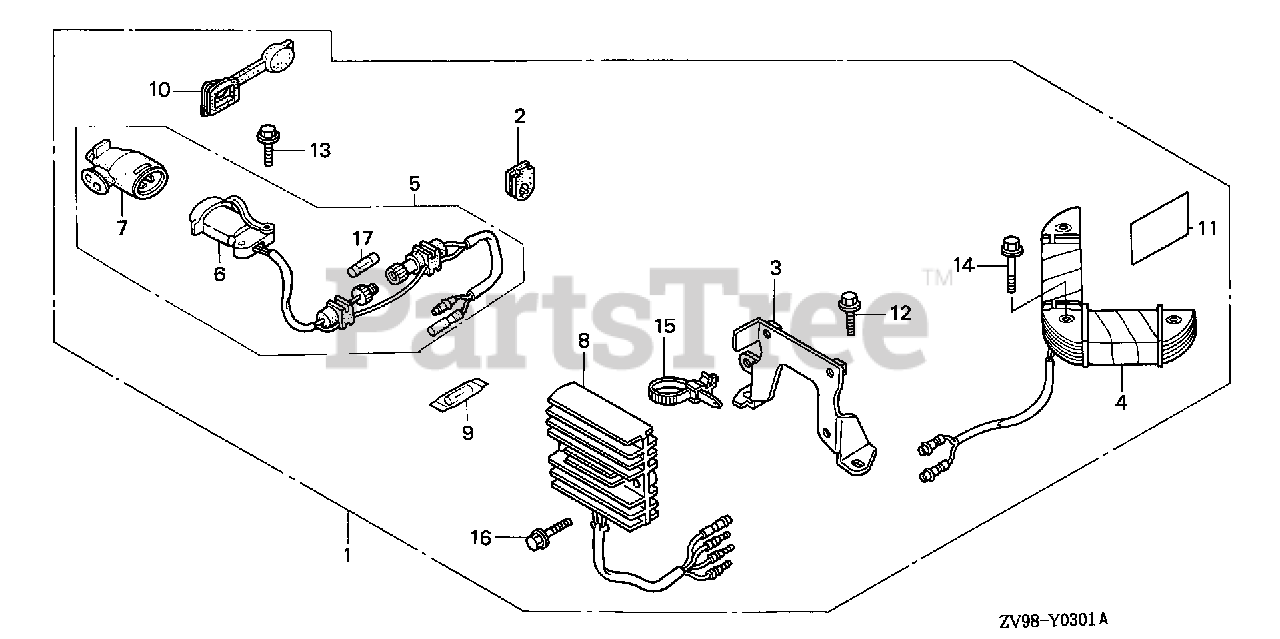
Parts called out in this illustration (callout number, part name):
1	RECEPTACLE KIT, CHARGE (10A)
2	GROMMET, WIRE
3	BRACKET, REGULATOR
4	COIL ASSY., CHARGE (12V-10A)
5	RECEPTACLE ASSY., CHARGE
6	RECEPTACLE
7	PLUG, RECEPTACLE
8	RECTIFIER ASSY., REGULATOR
9	FUSE, SPARE (15A)
10	GROMMET, CASE (LOWER) (C)
11	MARK, RECEPTACLE (10A)
12	BOLT, FLANGE (6X12)
13	BOLT, FLANGE (5X22)
14	BOLT, FLANGE (6X35)
15	STRAP, CABLE (118MM) (BLACK)
16	BOLT, FLANGE (6X20)
17	FUSE (15A)
